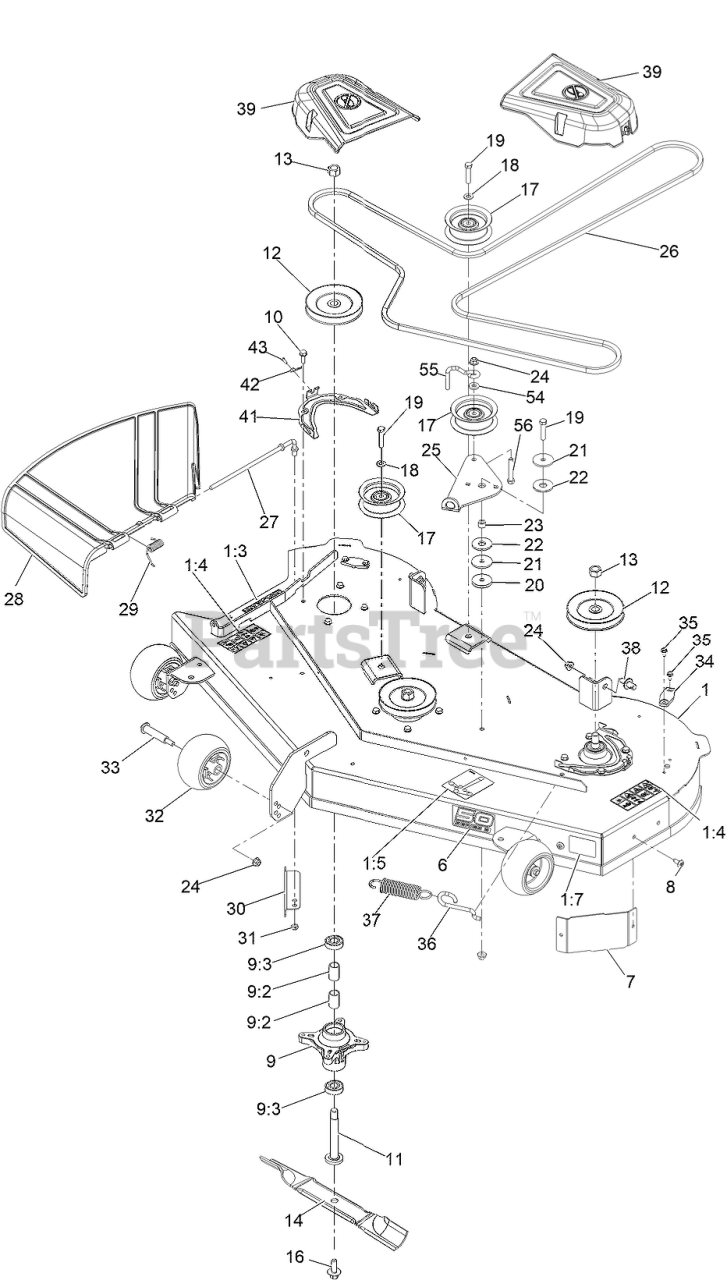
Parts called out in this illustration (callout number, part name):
1	50 INCH DECK AND DECAL ASM
1:3	Decal-Danger
1:4	DECAL-DANGER, DECK
1:5	DECAL-ROUTING, BELT
1:7	DECAL-SCALP, ANTI
6	Decal-50 Series 2
7	BAFFLE-CORNER
9	SPINDLE ASM
9:3	BEARING-BALL
10	SCREW-TAPTITE
11	SHAFT-SPINDLE
13	NUT-HEX
14	BLADE-HI LIFT
16	Bolt-Blade, Sems
17	PULLEY-IDLER, FLAT
18	WASHER-FLAT
19	SCREW-HH
20	WASHER-PLAIN
21	WASHER-REBOUND
22	WASHER-FRICTION, COMPOSIT
24	NUT-HF, NI
25	Arm-Idler
26	V-BELT
27	ROD-PIVOT
28	DEFLECTOR-DISCHARGE
29	SPRING-TORSION
30	BAFFLE-CUTOFF
32	ROLLER-SCALP, ANTI
33	BOLT-SHOULDER
34	COVER-WASHOUT PORT
35	SCREW-HWH
36	Hook-Return Spring
37	SPRING-EXTENSION
38	PIN-DECK
39	COVER-BELT
41	BRACKET-COVER, BELT
42	PIN-HAIR
54	SPACER-HUB, BLOWER
55	Belt Guide - Idler
56	SCREW-HH
